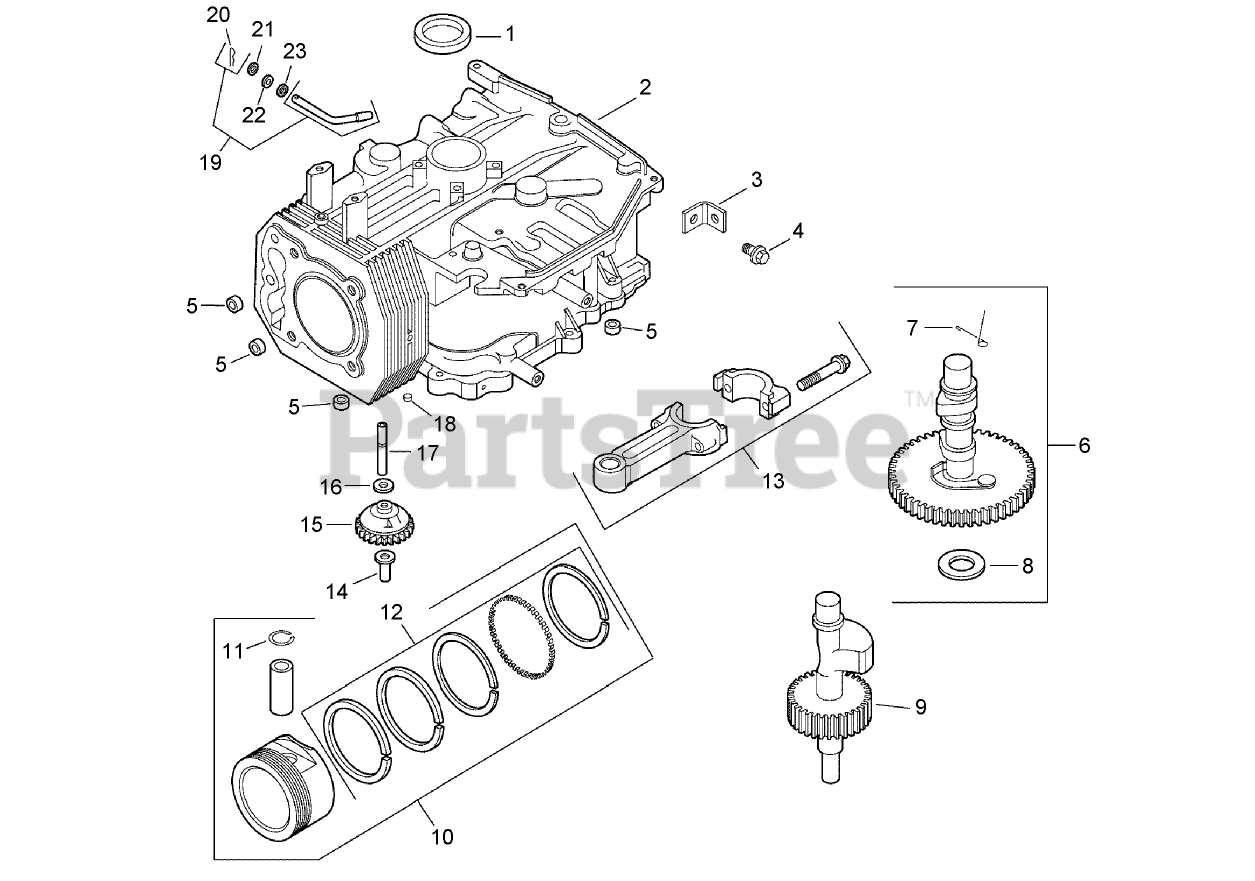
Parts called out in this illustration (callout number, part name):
1	Seal-Oil
3	Strap-Lifting
4	Screw-HF (M8x1.25x25)
5	Pin-Locating
6	Camshaft Kit (Incl. Ref. #7 and 8)
7	Spring-Actuating
8	SHIM-CAMSHAFT (BLUE .03)
8	SHIM-CAMSHAFT (RED .032)
8	SHIM-CAMSHAFT (YELLOW .034)
8	SHIM-CAMSHAFT (GREEN .036)
8	SHIM-CAMSHAFT (GRAY .038)
8	SHIM-CAMSHAFT (BLACK .04)
8	SHIM-CAMSHAFT (WHITE .028)
9	Shaft-Balance
10	Piston w/Ring Set (STD) (Incl. Ref. #11 and 12)
10	Piston w/Ring Set (.08)
10	Piston w/Ring Set (.25)
10	Piston w/Ring Set (.50)
11	Retainer-Pin, Piston
12	Ring Set (STD and .08)
12	Ring Set (.25)
12	Ring Set (.50)
13	Rod-Connecting (STD)
13	Rod-Connecting (.25)
14	PIN-REGULATING, GOVERNOR
15	Gear-Governor
16	WASHER-FLAT (6 MM)
17	SHAFT-GEAR, GOVERNOR
18	PLUG-CUP
19	Governor Cross Shaft Kit (Includes 20)
20	Clip-Pin, Hitch
21	WASHER-FLAT (1/4)
22	Seal-Cross Shaft, Governor
23	WASHER-FLAT (6mm)
